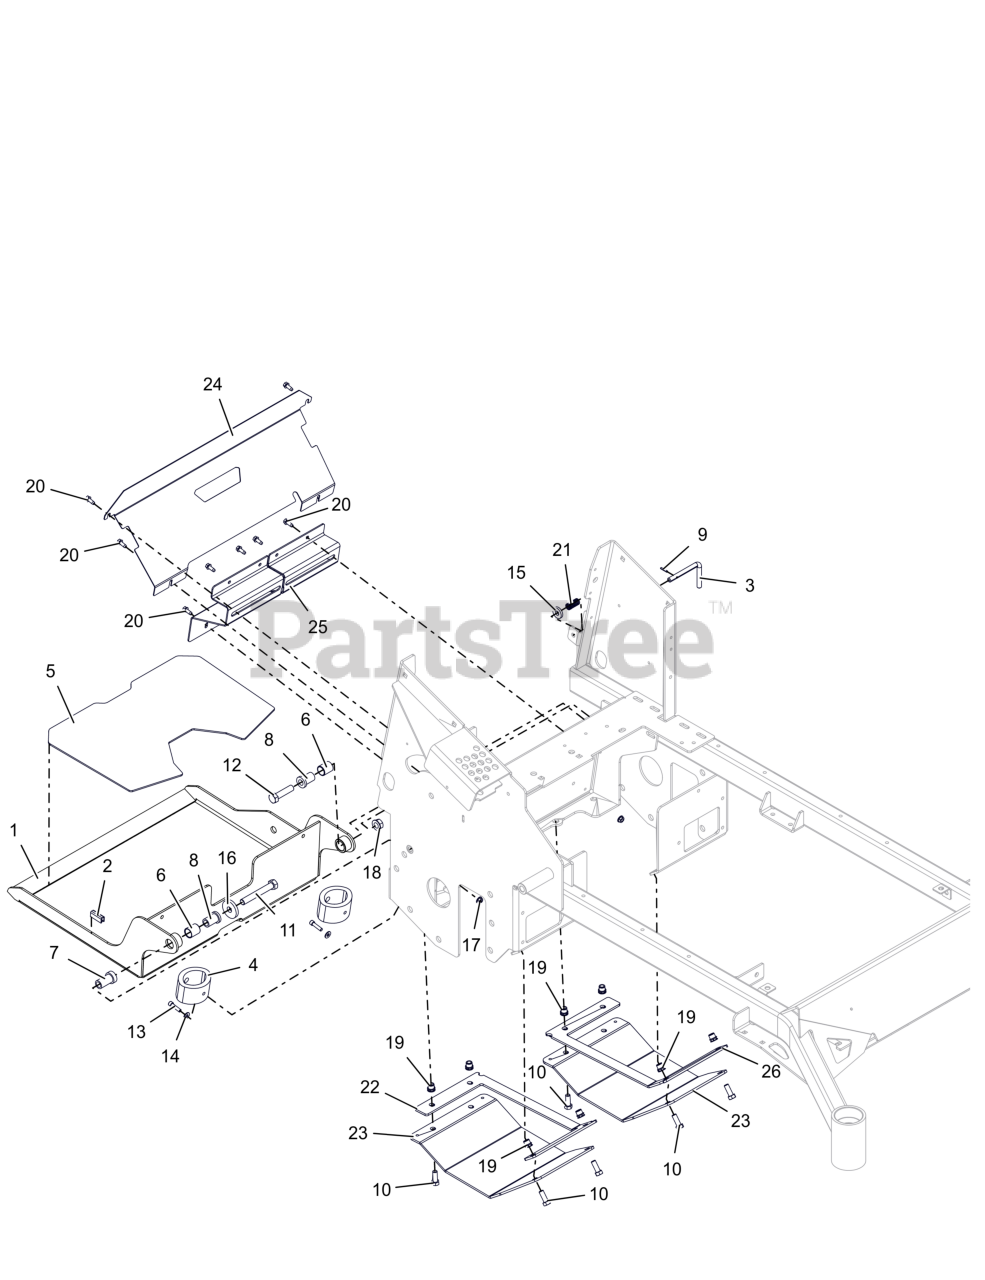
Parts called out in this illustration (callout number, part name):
1	WLDMT, OPERATOR PLATFORM (BLACK)
2	STRIP, COWL
3	PIN- PLATFORM LOCK
4	BUMPER, PLATFORM
5	TAPE, OPERATOR PLATFORM GRIP
6	BRG, .750 X .875 X 1.000
7	BSHG-FLG .515X.746X1.681X1.000
8	BSHG-FLG .515X.746X1.290X1.000
9	PIN-ROLL .125X.75
10	BLT, HEX .38-16X1.00 G8ZCCEP30
11	BLT, HEX .50-13X3.50F G5 ZCC
12	BLT, HEX .50-13X2.00 G5 ZCC
13	SCR, SKH .25-20X1.00
14	WSHR,FLT .281X.625X.065 ZCC
15	WSHR, FLT .406X1.00X.188 ZCC
16	WSHR-FL-STL .515X1.625X.250 YZ
17	NUT-LK-CTR-FLG .25-20 ZC120
18	NUT-LK-CTR-FLG .500-13 GG ZCC
19	NUT, THREADED INSERT .38-16 ZC120
20	SCR,TAP .25-20X.625 HWH ZCC
21	SPRING, COMPRESSION
22	PLATE, SKID TENSION (BLACK)
23	PLATE, SKID (BLACK)
24	PANEL- GUARD
25	GUARD- FOOT
26	PLATE- LH SKID TENSION
